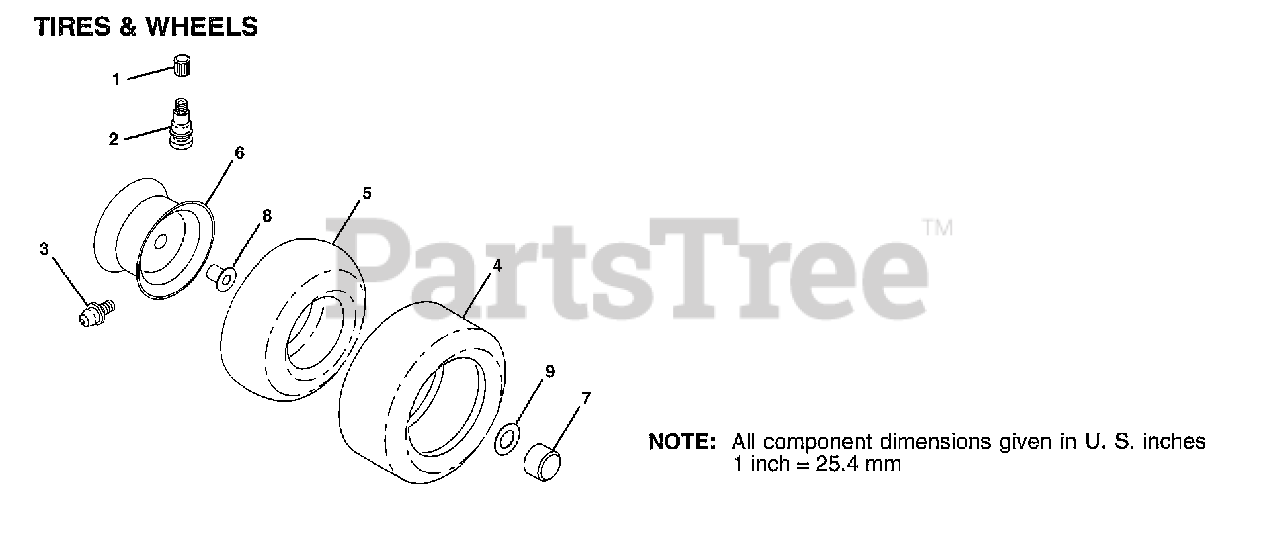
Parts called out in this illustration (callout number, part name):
1	VALVE CAP
2	VALVE STEM LT
3	FITTING LT
5	TUBE.5.3/4.5/6
5	TUBE.16X6.5/7.5-8
6	"RIM FRONT 6"""
6	"RIM ASM REAR 8"""
7	HUB CAP
8	"FLANGE, BEARING"
9	WASHER
